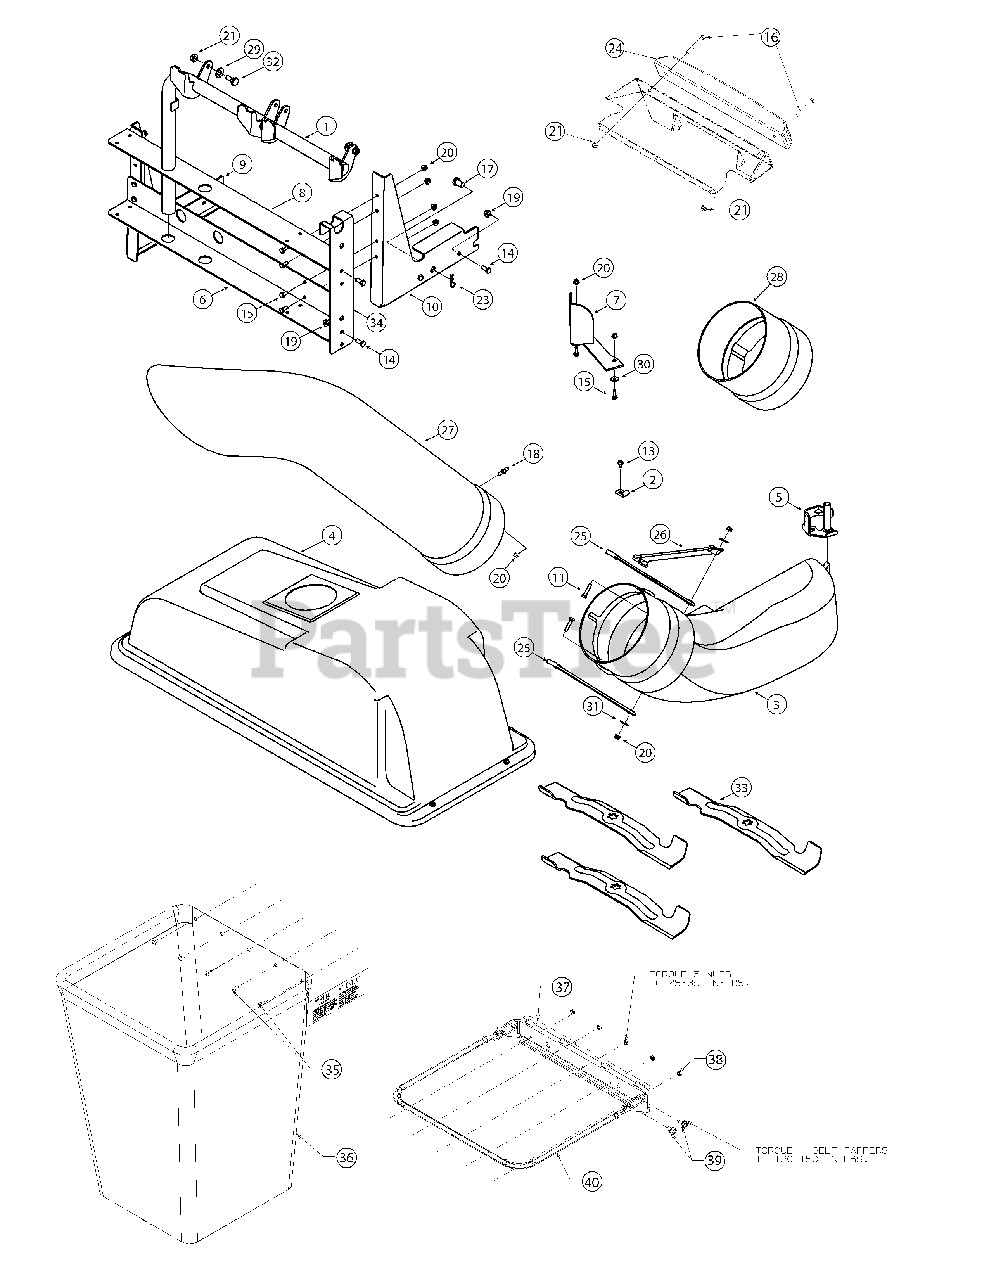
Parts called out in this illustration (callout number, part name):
2	Retainer Hook Bracket
3	Chute Elbow
4	Grasscatcher Cover Assembly
9	Catcher Mounting Bracket LH
13	TT Screw 1/4-20 x 0.5
14	Hex Bolt 5/16-18 x .75 Gr5
15	Hex Bolt 1/4-20 x 0.75 Gr5
16	Hex Bolt 3/8-16 x 2.75 Gr5
17	Clevis Pin
18	Grasscatcher Pin
19	Flange Lock Nut, 5/16-18 GrF
20	Flange Lock Nut 1/4-20 GrF
21	Flange Lock Nut 3/8-16 GrF
23	Cotter Pin
24	Weight Bar
25	Chute Strap
26	Chute Strap
27	Chute Tube
28	Chute Extension
29	Bell Washer
30	Bell Washer
31	Flat Washer
32	Shoulder Screw 3/8-16
35	Scr:Mach:#10-24:0.500
36	Grass Catcher Bag
38	Nut:Hex 10-24
39	Scr:TT:5/16-18:0.625
